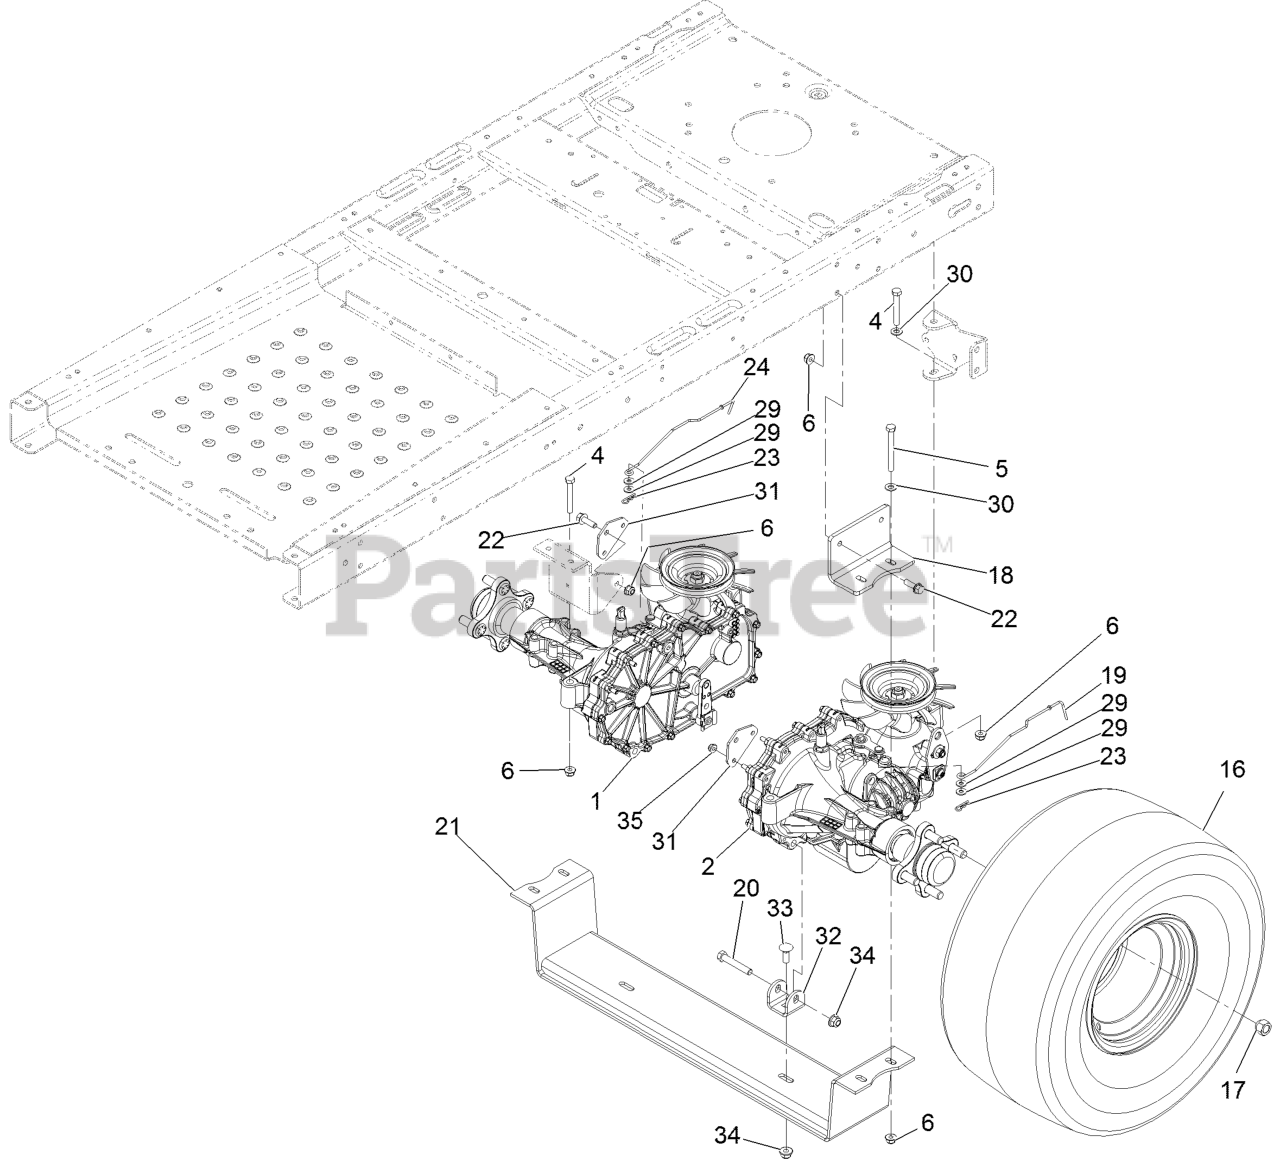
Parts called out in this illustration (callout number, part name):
1	RH HYDRO TRANSAXLE ASM
2	LH HYDRO TRANSAXLE ASM
4	SCREW-HH
5	SCREW-HH
6	NUT-HF, NI
16	ASM-WHEEL AND TIRE 20 X 8
17	NUT-LUG
18	MOUNT-HYDRO
19	ROD-BYPASS, LH
20	SCREW-HH
21	MOUNT-HYDRO
22	SCREW-HHF
24	ROD-BYPASS, RH
30	WASHER-PLAIN
31	PLATE-HYDRO MOUNT
32	TAB-HYDRO
33	BOLT-CARR
34	NUT-HF, NI
